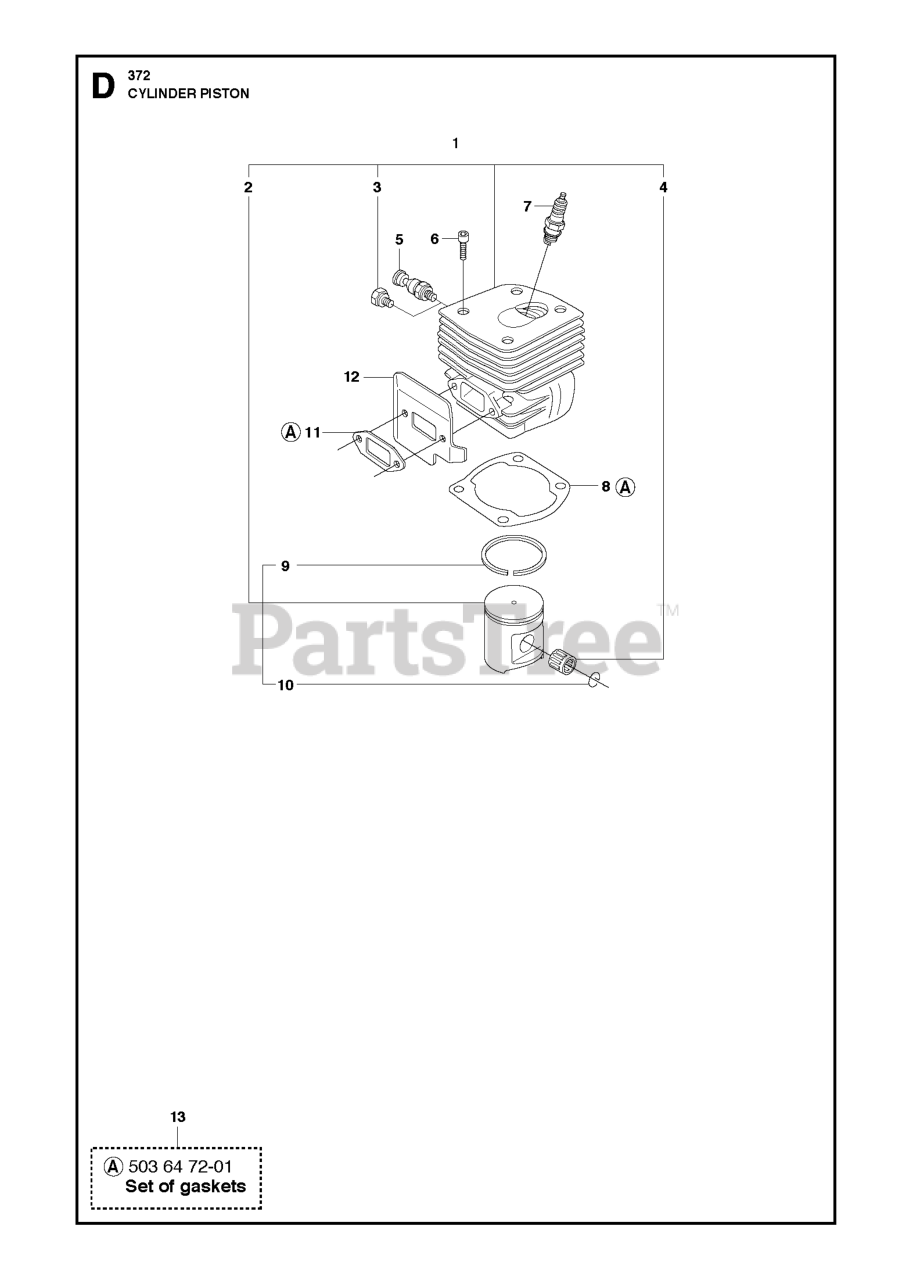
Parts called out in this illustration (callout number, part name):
1	CYLINDER ASSY
2	PISTON CPL 50 MM
2	PISTON ASSY
3	CYLINDER PLUG
4	NEEDLE BEARING PISTON PIN 12X1
5	DECOMPRESSION VALVE
6	SCREW ITXSCM M5X25 T27 12.9 T
7	SPARK PLUG M14X1.25 NGK BPMR7A
9	RP PISTON RING
9	PISTON RING
10	WRIST PIN CLIP
13	GASKET SET
